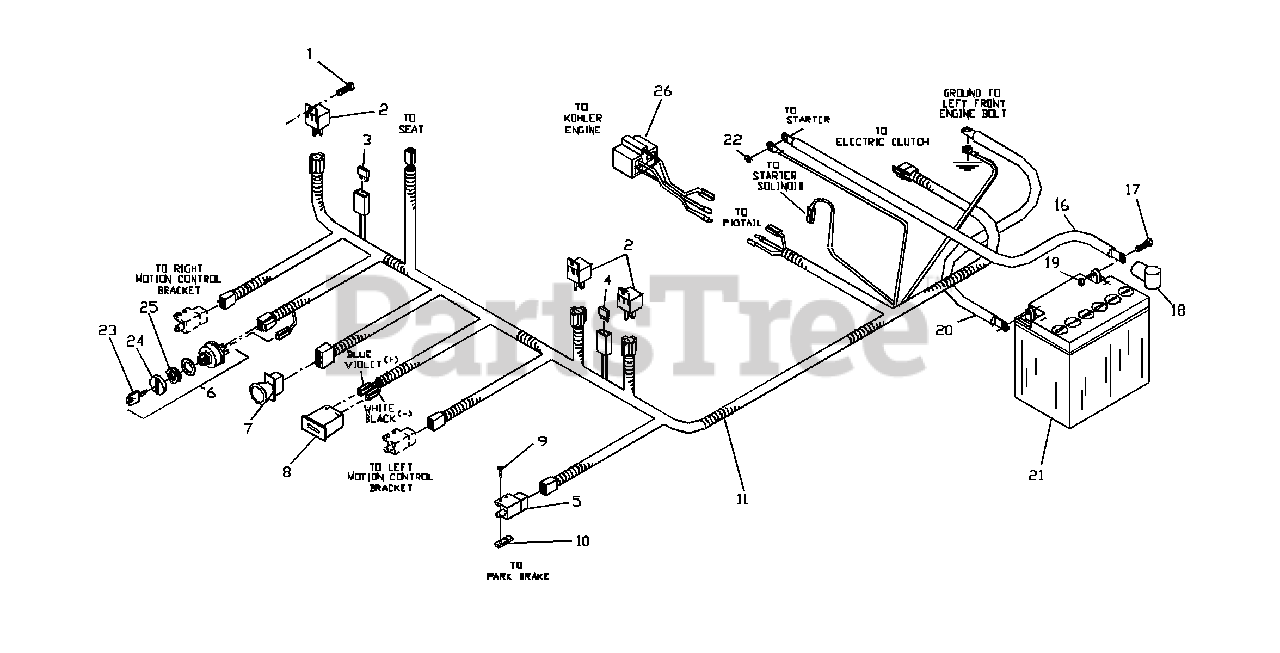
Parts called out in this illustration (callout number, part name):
1	#10 X 1/2 SELF TAPPING
3	7.5 AMP 32 VOLT ATO FUSE
4	20 AMP 32 VOLT ATO FUSE
5	INTERLOCK SWITCH
6	IGNITION SWITCH
7	BLADE SWITCH
8	HOUR METER
9	#10-24 X 5/8
10	TAPPED PLATE
11	WIRING HARNESS
12	NUT 1/4C CENTERLOCK
16	CABLE POSITIVE, LONG
17	HCS 5/16C X 3/4
19	NUT 5/16C CENTERLOCK
20	CABLE NEG.
21	BATTERY
22	NUT 1/4C NYLOC
23	KEY, PADDED
26	PIGTAIL FOR ENG. WIRING
